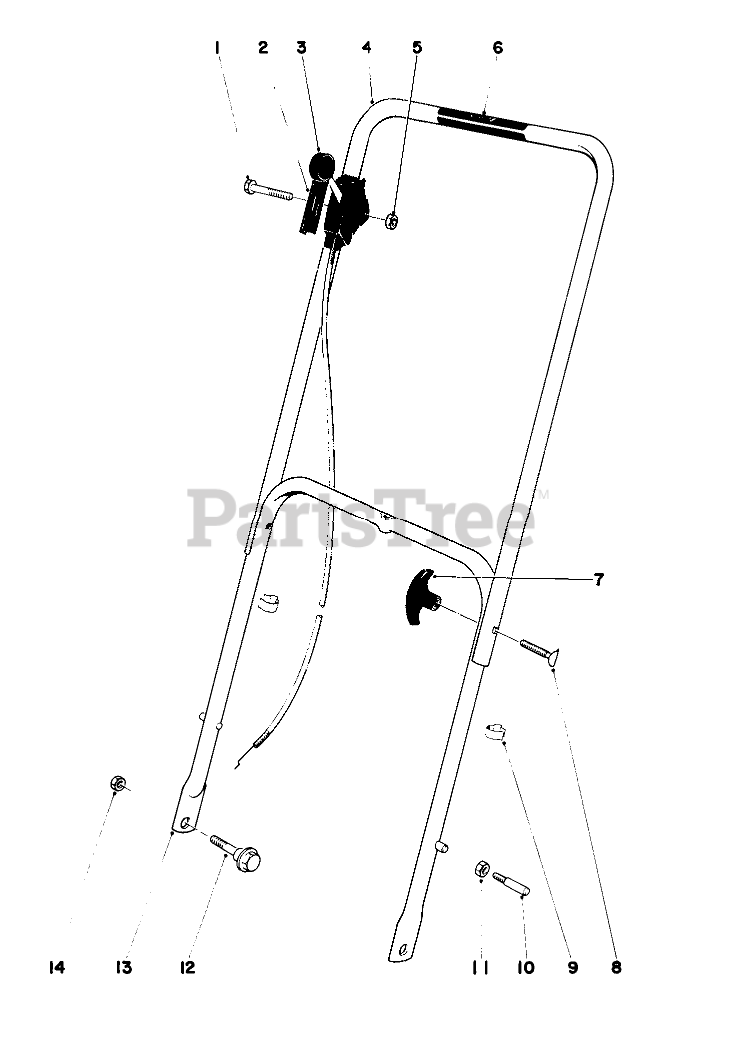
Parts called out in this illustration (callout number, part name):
1	SCREW-HH
2	Decal-Throttle
3	Throttle Control
4	Upper Handle
5	NUT-LOCK
6	Decal
8	HANDLE SCREW
9	BOWDEN CLIP
10	HANDLE PIN
11	Nut
12	SCREW-SHOULDER
13	19 LOWER HANDLE ASM
14	Nut
